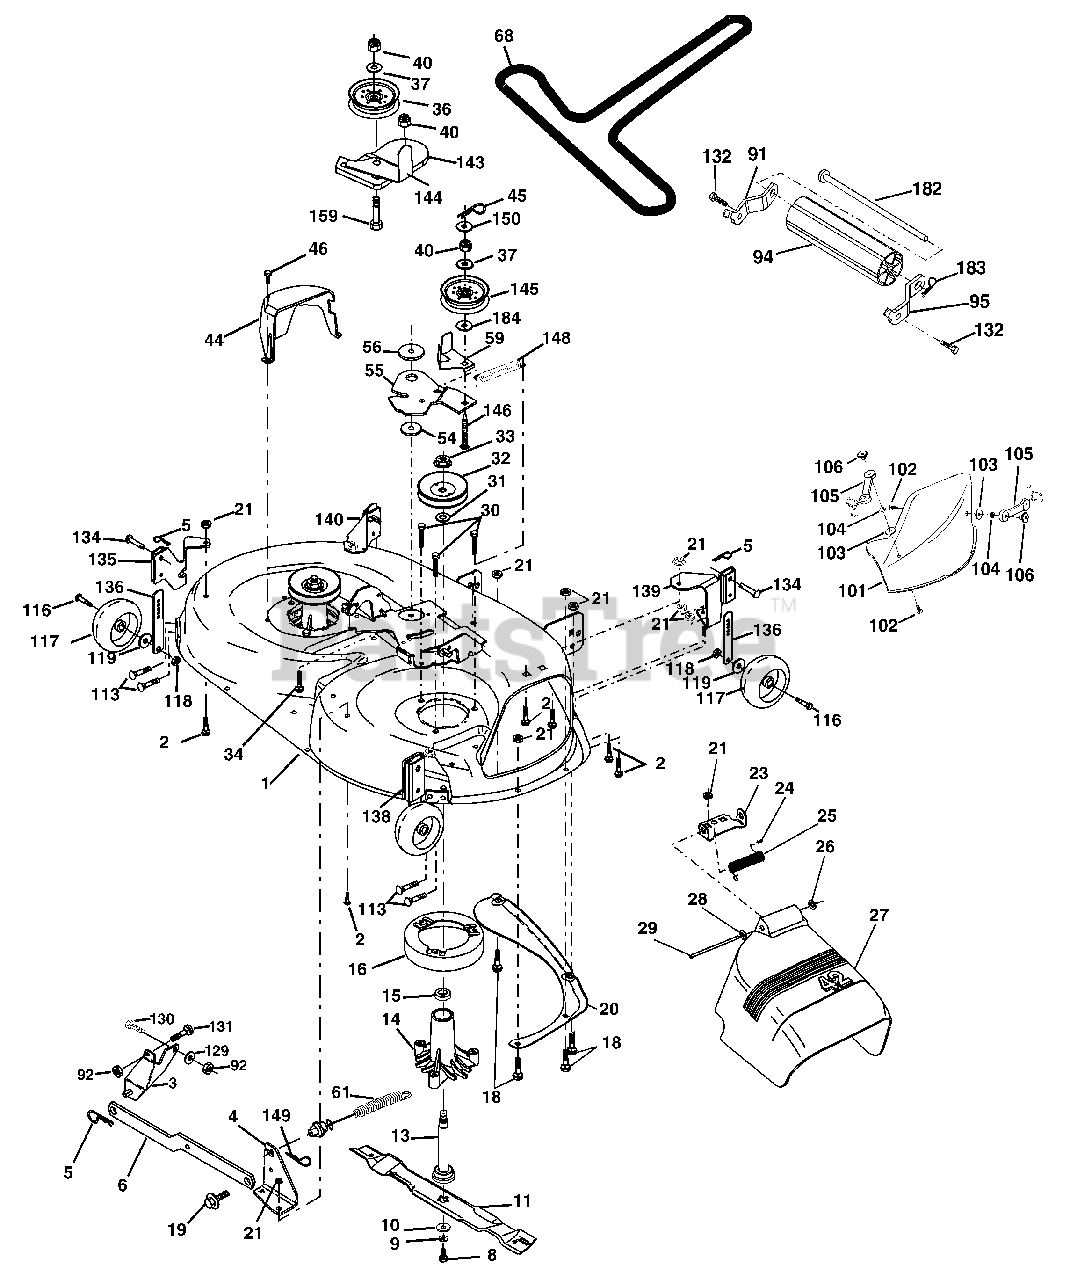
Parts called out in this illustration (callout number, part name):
1	Mower Deck Assembly, 42"
2	Bolt
3	Bracket Asm Fr. Sway Bar 3/42
4	Bracket Asm Deck 42" Sway Bar
5	Retainer Spring
6	Bar Sway Deck
8	Bolt 3/8-24 x 25 Grade 8 patched
9	Washer, Lock
10	Washer, Hardened
11	Blade, Mulching 42" Std
11	Blade Mulching 42" Premium
11	Blade Mower 42" Hi-Lift
13	Shaft Assembly, Mandrel, Vented
14	Housing, Mandrel, Vented
15	Bearing, Ball, Mandrel
16	Stripper, Mandrel Deck
18	Bolt, Carriage 5/16-18 x 3/4
19	Bolt, Shoulder
20	Baffle, Vortex
21	Nut
23	Bracket, Deflector Mower 42"
24	Cap, Sleeve 80 x 112 Blk Mower
25	Spring, Torsion, Deflector 2 52
26	Nut, Push Phos & Oil
27	Shield, Deflector 42" Blk
28	Washer 11/32 x 5/8 x 16 Gauge
29	Rod, Hinge 42" 6 75 W/G
30	Screw Thdrol Washer Head
31	asher, Spacer Mower Vented
32	Pulley, Mandrel
33	Nut, Toplock Flange
34	Bolt
36	Pulley, Idler, Flat
37	Washer 13/32 x 13/16 x 16 Gauge
40	Nut
44	Guard, Mandrel, LH
45	Retainer
46	Screw, Thdrol 1/4-20 x 5/8 T
54	Washer, Hardened
55	Arm, Idler
56	Spacer, Retainer
59	Guard TUV Idler
61	Spring Ext. Elect Clutch
68	V-Belt, 42" Mower
91	Bracket Asm Noseroller LH
92	Nut Lock Hex W/Ins 3/8-16unc
94	Roller Nose 38 & 42
95	Bracket Asm Noseroller RH
101	Mulcher Cover
102	Screw Pan HD Phillip 10-24 x 5/8
103	Washer, Flat
104	Washer, Lock
105	Latch Assembly
106	Nut, Weld
113	Screw Tapping 5/16 - 18 x 3/4
116	Bolt, Shoulder
117	Wheel, Gauge
118	Nut Centerlock 3/8-16
119	Washer 3/8 x 7/8 x 14 Ga.
129	Washer 13/32 x 13-16 x 12 Ga.
130	Bolt Fin Hex 3/8-16unc x 1 Gr. 5
131	Bolt RDHD 3/8-16unc x 1
132	Screw 3/8-16 x .75
134	Pin Head Pivet
135	Brkt Asm Whl Ga. R.LH
136	Bar Adjusting Gauge Wheel
137	Bolt Carr. 5/16-18 x 5/8
138	Brkt Asm Whl Ga. R. RH
139	Brkt Asm Whl Ga. F. RH
140	Brkt Asm Whl Ga. F. LH
143	Bracket Arm Idler 42"
144	Keeper Belt 42" Clutch Cable
145	Pulley Idler Flat
146	Bolt Carriage Idler
148	Spring Return Idler
149	Retainer Spring Yellow
150	Washer 9/32 x 3/4 x 16 Ga.
159	Bolt Rdhd Sqn 3/8-16 UNC x 1-3/4
182	Rod Roller Nose
183	Retainer Spring
184	Washer 13/32 x 7/8 x 10 Ga.
